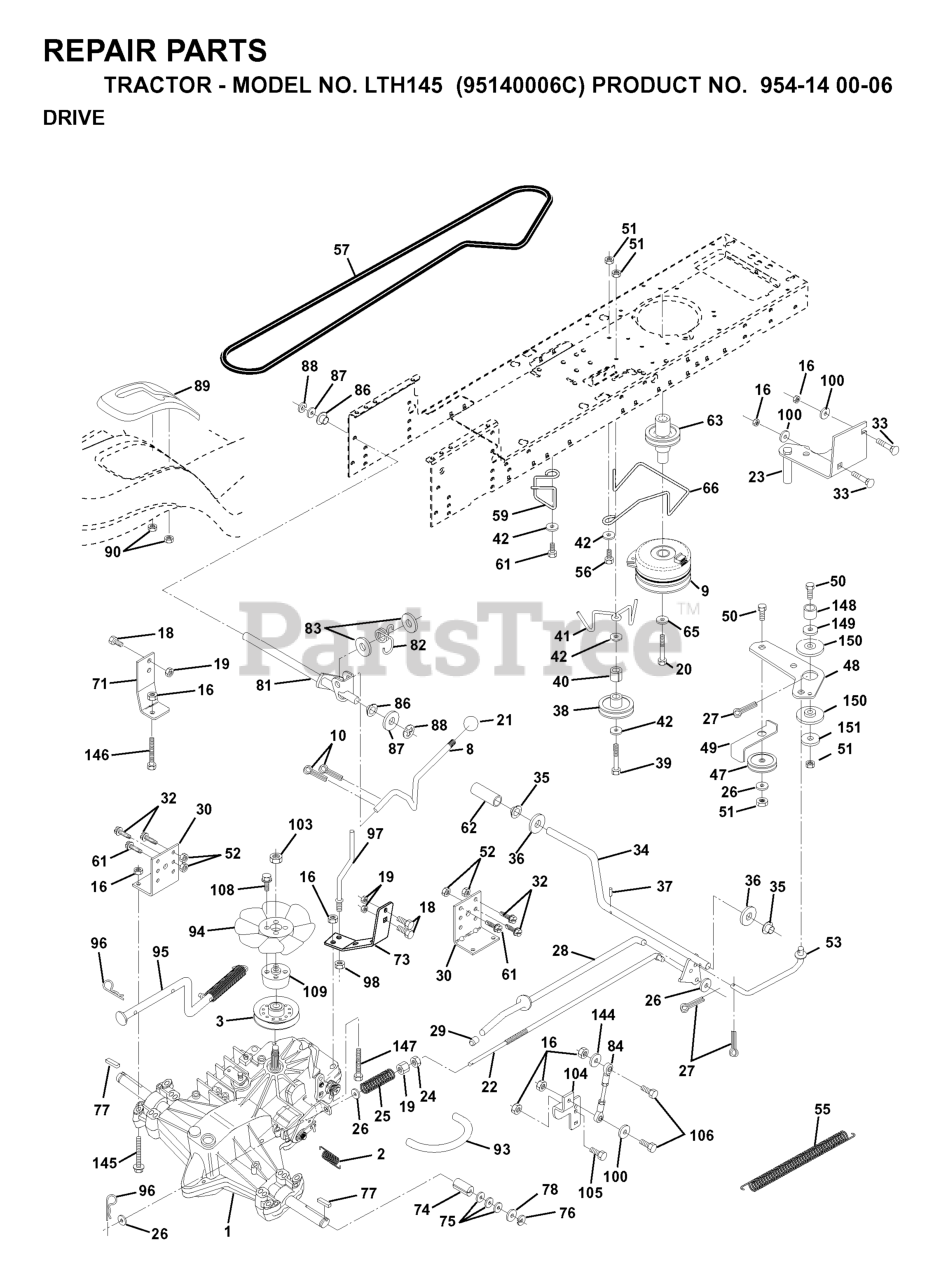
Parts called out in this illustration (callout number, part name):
1	TRANSAXLE.HYDRO.319-0500.LR
2	SPRING BRAKE
3	PULLEY.4.20.HYDRO
8	ROD SHIFT FENDER
9	CLUTCH.ELECT.EVX.
10	PIN COTTER
16	NUT.71038.31-18.HEX.NYLOCK
19	NUT
20	BOLT HEX
21	KNOB.DUCKHEAD.1/2
22	ROD BRAKE HYDRO
23	BRACKET, ASM CLUTCH MTG
24	NUT
25	SPRING ROD LT
26	WASHER
27	COTTER PIN
28	ROD BRAKE PARK LT
29	PLUNGER CAP
30	BRACKET TRANSAXLE
32	BOLT
33	RP BOLT 5/16-18 X3/4 ZN/YEL GR
34	SHAFT, FOOT PEDAL
35	BEARING.NYLON
37	DRIVE PIN
38	PULLEY.IDLER.FLAT
41	KEEPER, BELT IDLER
42	WASHER
47	IDLER PULLEY
48	BELLCRANK, CLUTCH
49	RETAIN BELT
50	BOLT
52	LOCKNUT
53	LINK, CLUTCH LT
55	SPRING, RETURN LT
57	DRIVE BELT
59	KEEPER CENTER SPAN
61	SCREW
62	PEDAL COVER T
63	ENGINE PULLEY
65	LOCKWASHER
66	BELT KEEPER
71	STRAP TORQUE LH HYDRO
73	STRAP TORQUE RH HYDRO
74	SPACER SPLIT
77	SQUARE KEY
82	SPRING,TORSION
83	WASHER
84	ROD, TIE HYDRO
89	SHIFT CONSOLE
90	NUT.PUSH.3/16
93	LINE FUEL HYD 4"
94	FAN 7" HYDRO
95	CONTROL ARM, BYPASS HYDRO
96	RETAINER M
97	KEEPER BELT RH
100	WASHER M
103	NUT.HEX.1/2-20
104	ARM, CONTROL HYDRO
106	BOLT.5/16-18X1-1/4 FULL.THREAD
109	ADAPTOR FAN HYDRO
144	Washer 11/32 x 5/8 x 16 Ga SD
146	Bolt Hex Flanged 5/16-18 Unc x 2
147	Bolt Hex Flanged 5/16-18 Unc x 2
149	SPACER RETAINER
150	BUSHING NYLON COLLERED
